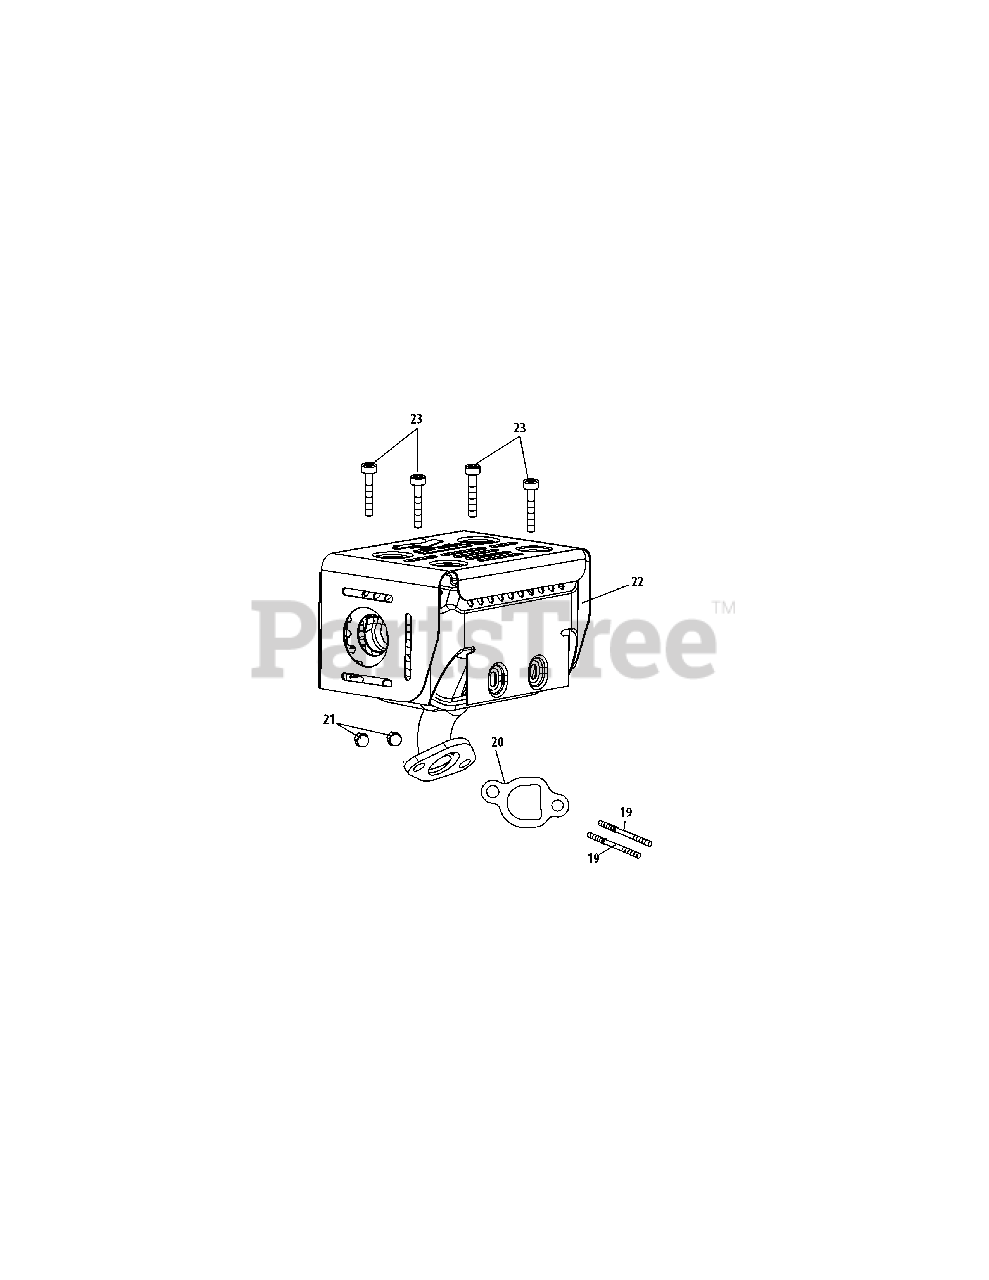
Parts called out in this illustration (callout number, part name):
19	Muffler Stud M8×36
19	Muffler Stud Assembly
20	Exhaust Pipe Gasket
22	Muffler Assembly
23	Bolt M5×10
